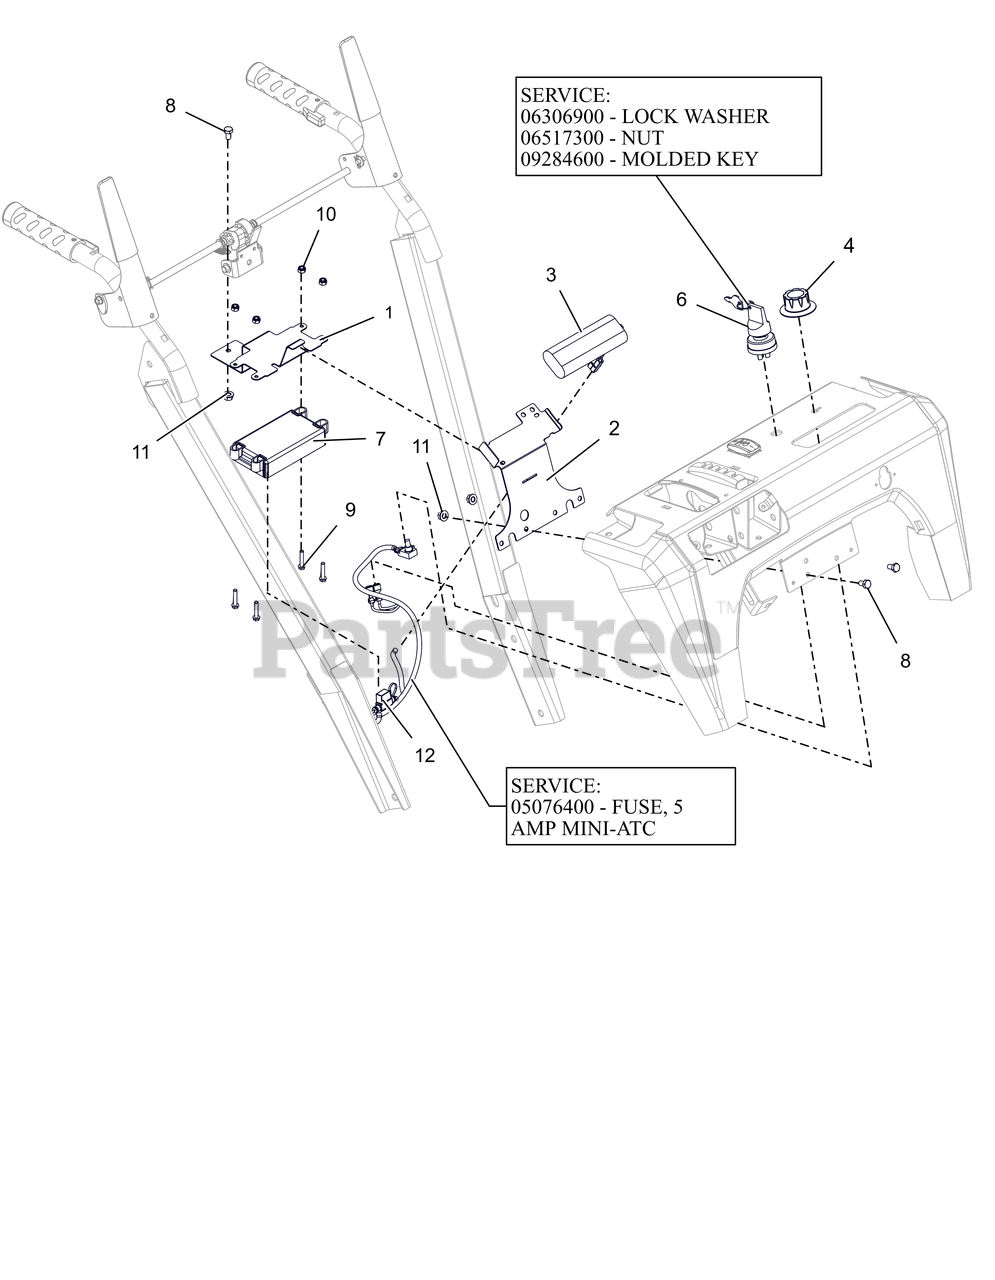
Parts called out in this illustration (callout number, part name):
1	BRACKET, ENGINE EFI-LCT LOWER
2	BRACKET, ENGINE EFI-LCT UPPER
3	BATTERY, SNOW EFI - 7.2V
4	KNOB, CONTROL - 2.063 ID
6	IGNITION SWITCH ASM - 2 POS
6	WSHR-LK-INT .625X.045 YWZC
6	NUT-PANEL .625-32 GRECO
6	KEY W/ SHIELD
7	ECU SERVICE LCT/CSI - 420CC
8	@BLT-HEX .25-20X.50 GR5 YWZC
9	@SCR-MCH 10-24X1.00 HWH YWZC
10	@NUT-LK-NYL 10-24 W/INSRT YWZC
11	@NUT-LK-TOP-FLG .25-20 YWZC
12	HARNESS,WIRE - EFI ECU
12	FUSE, 5 AMP MINI-ATC
